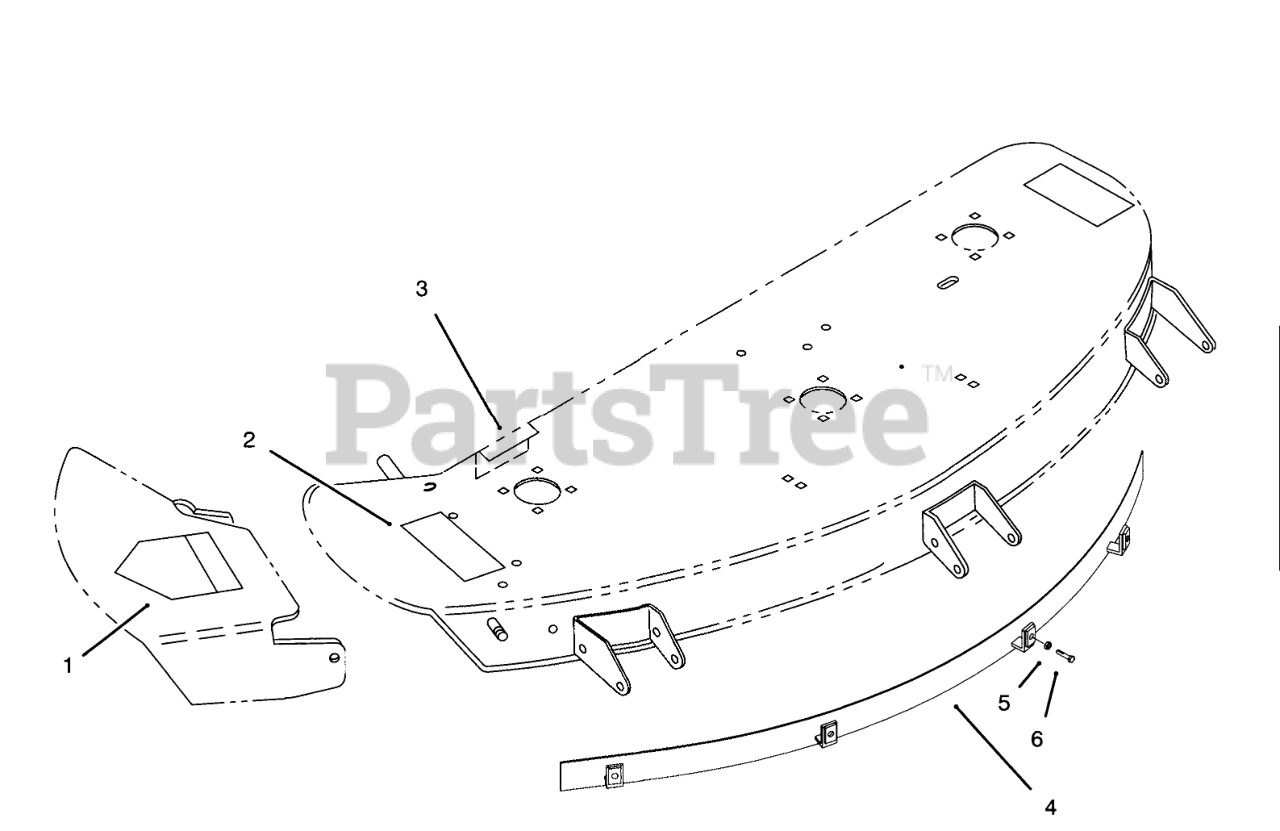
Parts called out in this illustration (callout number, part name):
1	DECAL-DANGER
2	DECAL-DANGER
3	Decal-Height Belt
5	NUT-JAM
